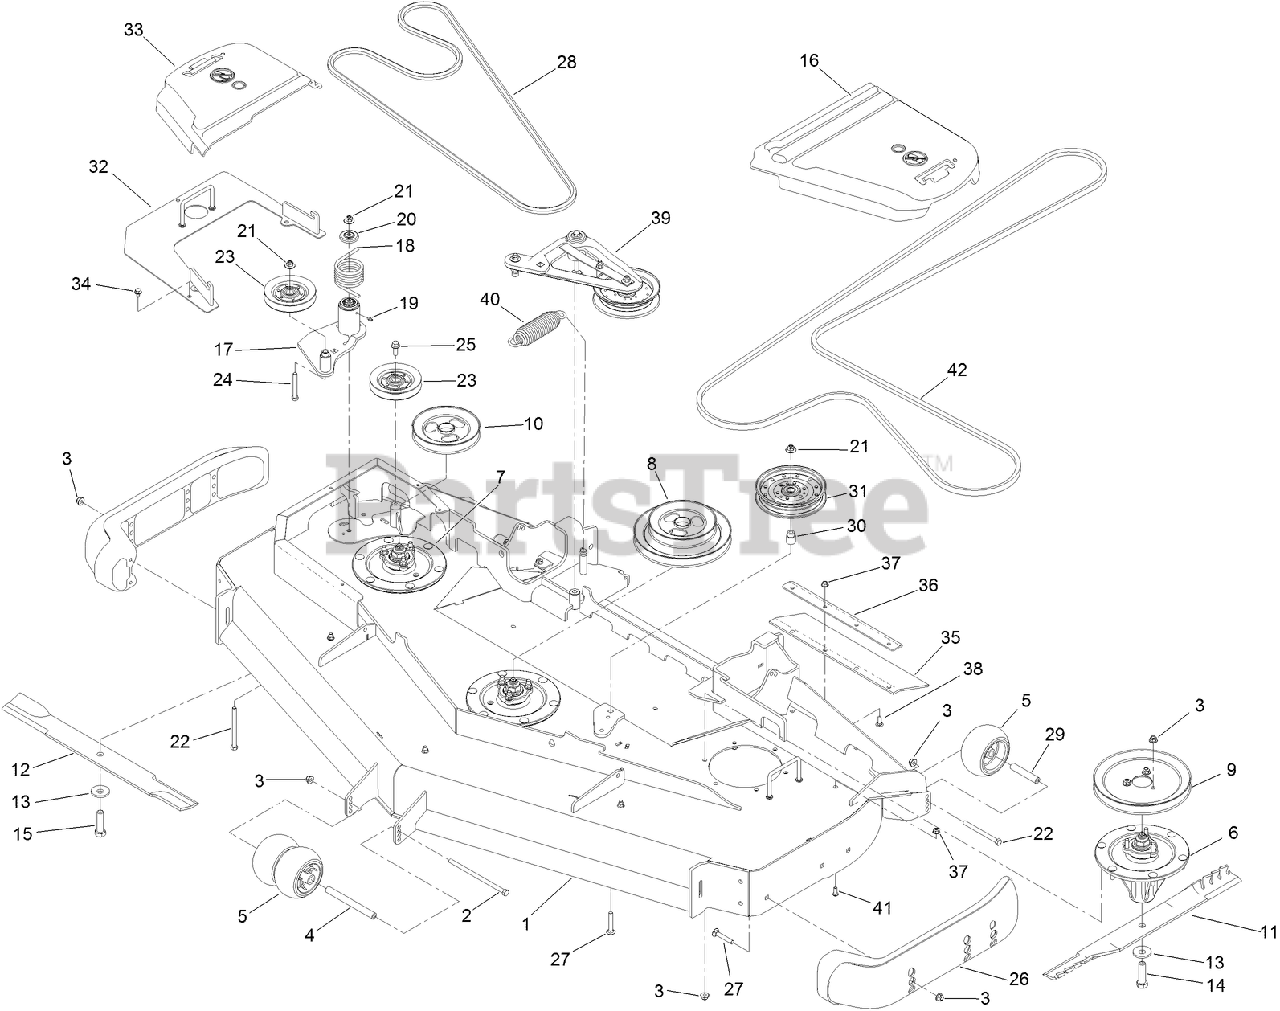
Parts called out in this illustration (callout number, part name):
1	DECK DECAL ASM
2	SCREW-HH
3	NUT-HF, NI
4	SPACER-WHEEL
5	ROLLER-SCALP, ANTI
6	SPINDLE ASM
7	LH SPINDLE ASM
8	PULLEY ASM
9	SHEAVE
10	PULLEY
11	BLADE-ATOMIC, 24.5IN
12	BLADE-ROTARY, 24.5IN LOW FLOW (COUNTER ROTATION)
13	Washer-Blade Bolt, Heavy
14	SCREW-BLADE
15	SCREW-BLADE, LH
16	COVER-BELT, LH
17	IDLER ASM
18	SPRING-TORSION
19	FITTING-GREASE
20	GUARD-TOP
21	NUT-FLANGE, NI
22	SCREW-HH
23	SHEAVE
24	SCREW-HH
25	SCREW-HHF
26	SKID-BUMPER, DECK
27	SCREW-CARR
29	TUBE-SPANNER
30	Bushing, Idler
31	PULLEY-IDLER, FLAT
32	COVER-REVERSE DRIVE
33	COVER-BELT, RH
34	SCREW
35	GUARD-TIRE
36	SUPPORT-OUTER FLAP
37	NUT-HF, NI
38	SCREW-CARR
39	DECK IDLER ASM
40	SPRING-EXTENSION
41	SCREW-HSBH
